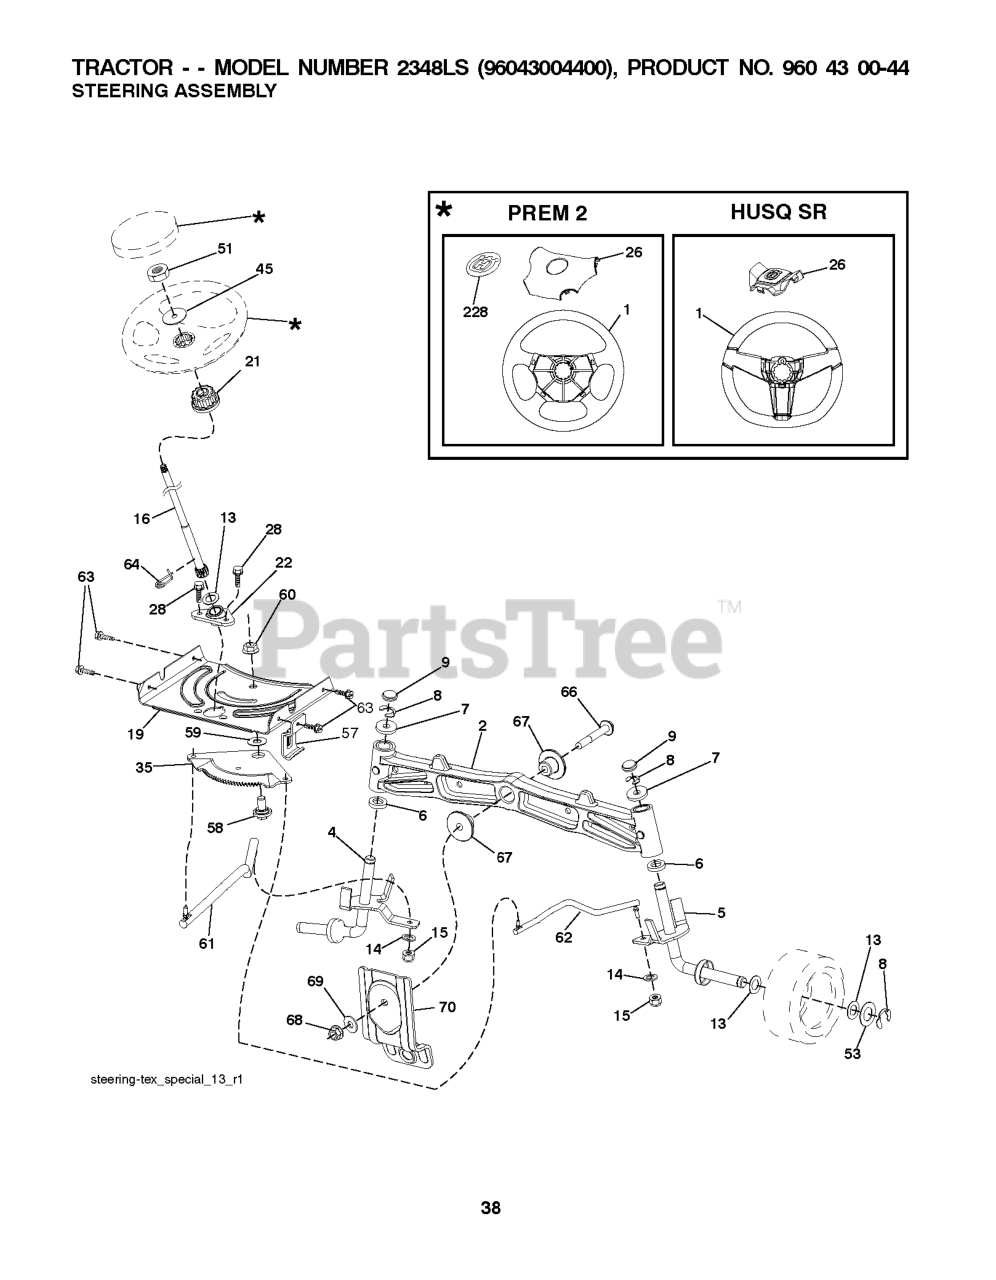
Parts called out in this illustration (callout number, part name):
1	RP WHEEL.STEER.HUSQ.PREM.OVMLD
2	AXLE.CAST.IRON
4	SPINDLE.WELDED.LH.15"TEX
5	SPINDLE.WELDED.RH.15"T
6	THRUST WASHER
7	WASHER
8	RING CLIP
9	CAP.SPINDLE.BLACK
13	WASHER
14	WASHER, LOCK 3/8
15	NUT CROWNLOCK 3/8-24
16	SHAFT, STEERING
19	PLATE.STEER.DDL.NLT/NG
21	ADAPTER, WHEEL STNG..
22	BUSHING.ASM.STEERING.A
26	RP INSERT.CAP.WHL.STRG.HUSQ.
28	SCREW, 3/8-16X3/4
35	GEAR.SECTOR.PLATE.DDL.
45	WASHER 9/16"ID, 2 3/8"OD
51	NUT.HEX.1/2-20
53	WASHER.HARDENED
57	BRKT.UPSTOP.GT/LT.TEX
58	BOLT.SHOULDER.SECTOR.P
59	WASHER.THURST.SECTOR.S
60	NUT FLANGE LOCK 5/8-11
61	DRAGLINK.LH.BALLSTUD.D
62	DRAGLINK.RH.BALLSTUD.D
63	SCREW
64	RETAINER.CLIP.SPRING.S
66	BOLT HEX FGHD 7/16-14 X 3 SERR
67	BUSHING.PM.FRONT AXLE
68	NUT.LOCK.FLANGE.7/16
69	WASHER.1.5X.505X.118
70	BRKT.DECK.SUSPENSION.F
228	DECAL.WHEEL.STRG.LGN.H
